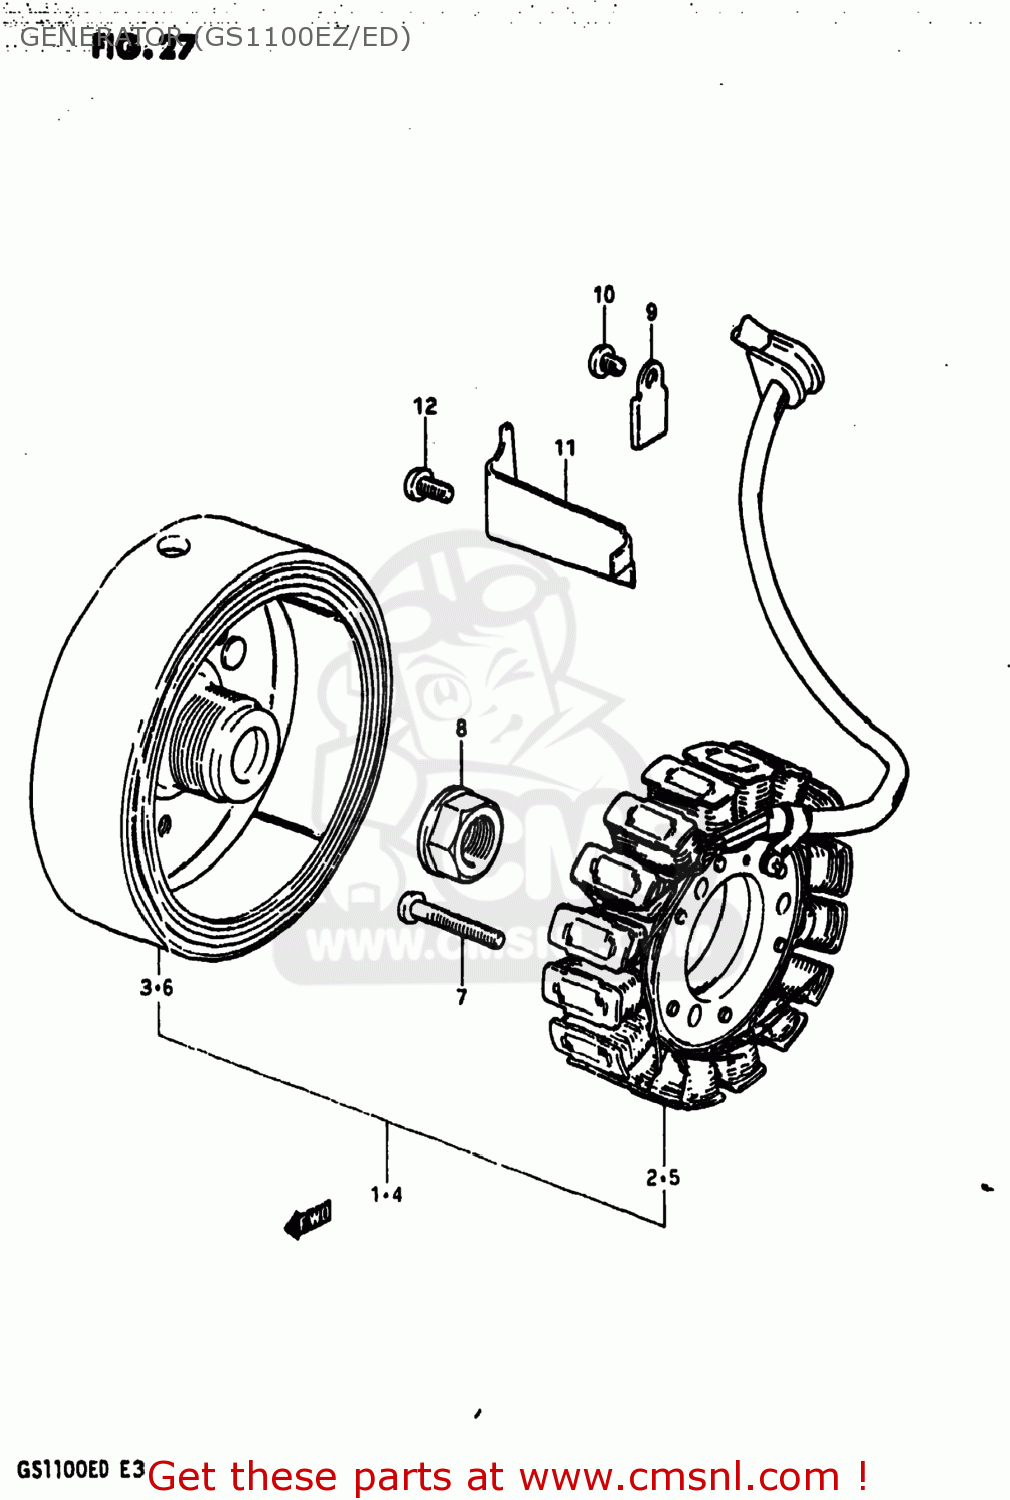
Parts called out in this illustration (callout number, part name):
1	GENERATOR ASSEMBLY
2	STATOR ASSEMBLY
3	ROTOR ASSY
4	GENERATOR ASSEMBLY
5	STATOR ASSEMBLY
6	ROTOR ASSEMBLY
7	SCREW 6X30
8	NUT,GENERATOR ROTOR
9	CLAMP,GENERATOR LEAD WIRE
10	SCREW
11	CLAMP,GENERATOR LEAD WIRE
12	SCREW
